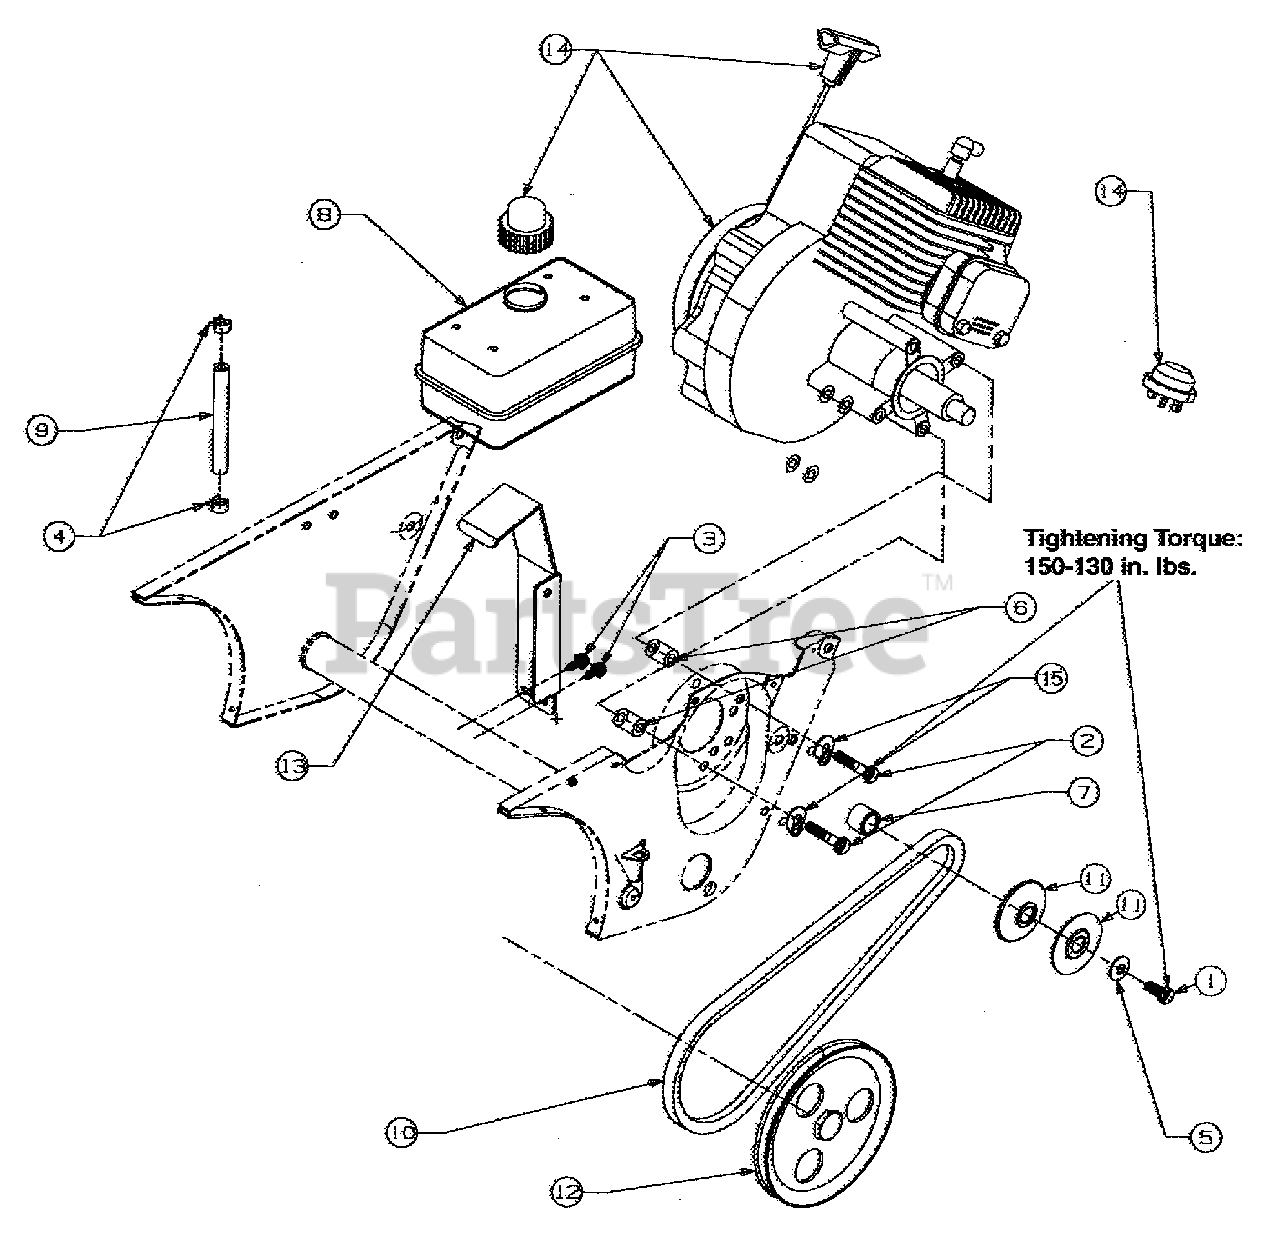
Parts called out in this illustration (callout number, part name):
1	Screw-Hex Cap
2	Screw-Hex Cap
3	Screw-Washer
4	Clamp-Hose
5	Washer-Bell
6	Spacer
7	Spacer
8	Tank-Fuel
9	Hose-Fuel 12"
10	V-Belt
11	V-Pulley Half
15	Washer-Lock
